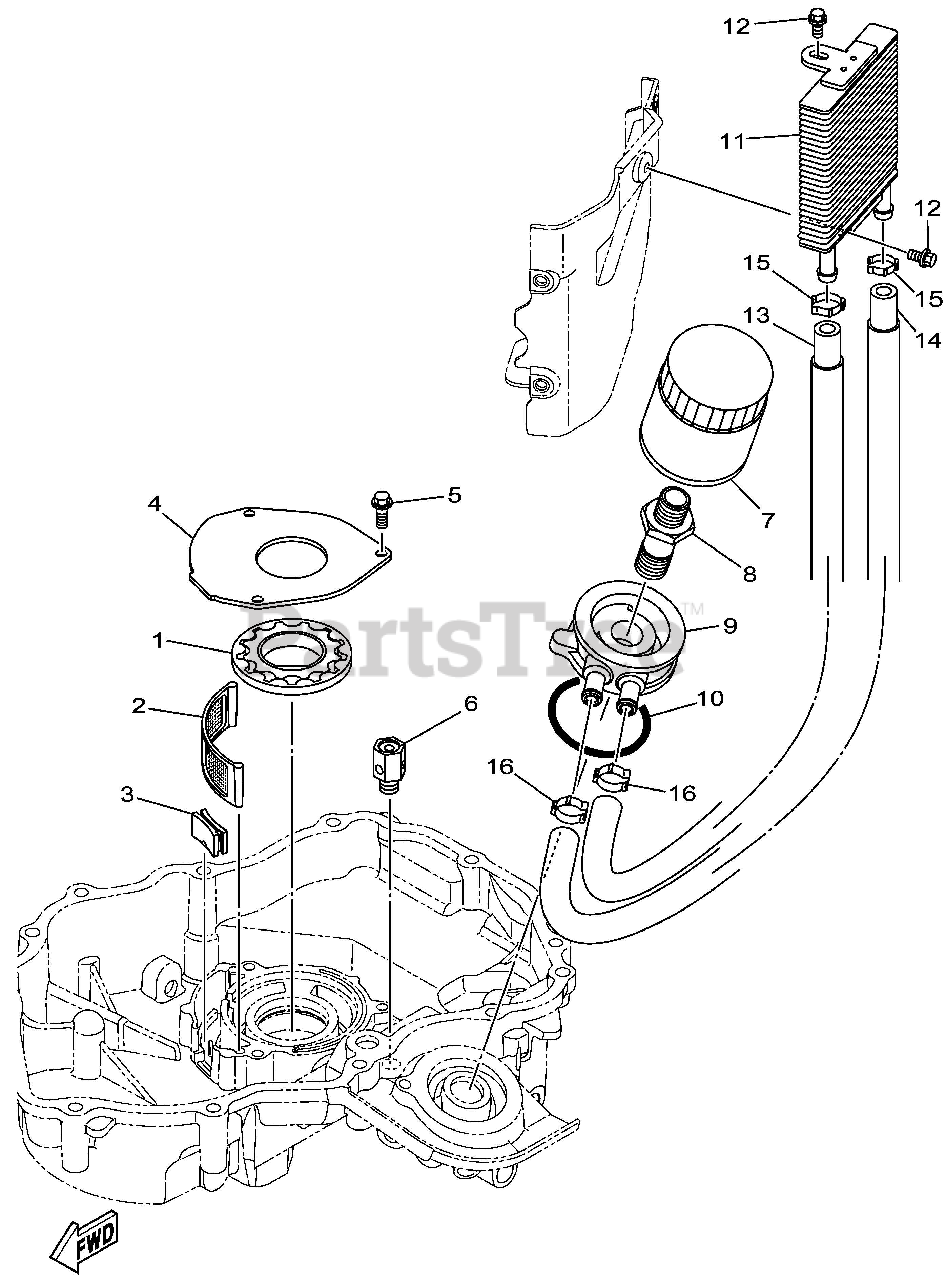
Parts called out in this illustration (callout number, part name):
1	ROTOR ASSY 1
2	STRAINER, OIL
3	COVER, STRAINER
4	COVER, PUMP
5	BOLT, FLANGE
6	RELIEF VALVE ASSY
7	FILTER, OIL - YAMAHA 824
8	BOLT, UNION
9	ADAPTER
11	OIL COOLER ASSY
12	BOLT, FLANGE
13	HOSE, OIL 1
14	HOSE, OIL 2
